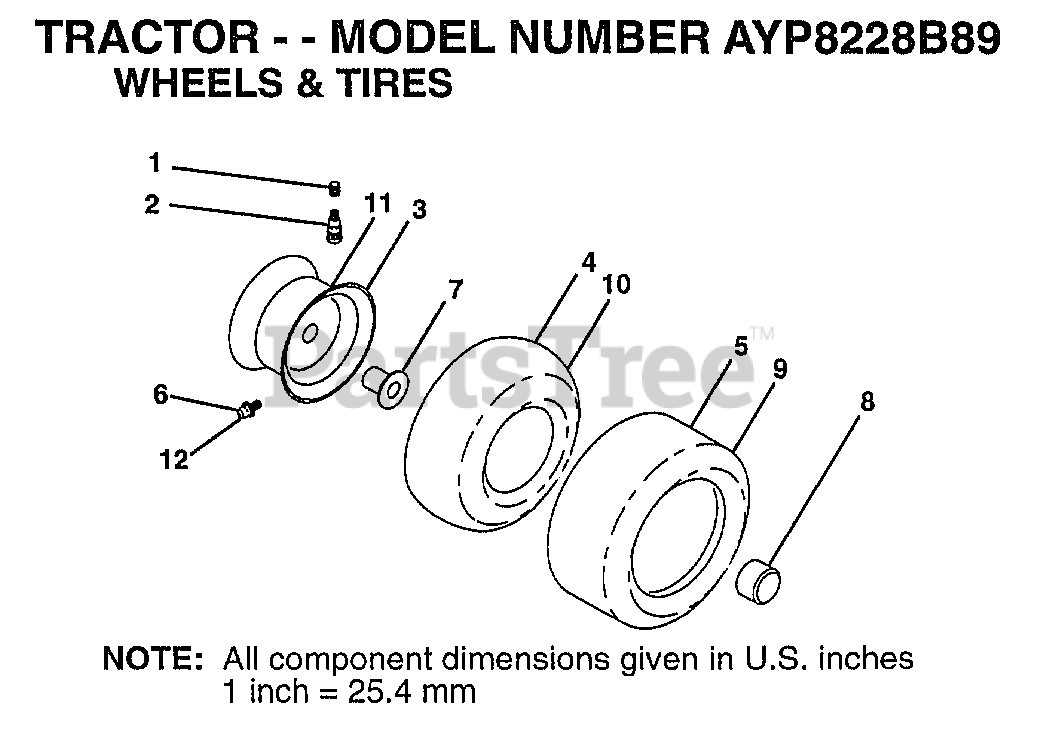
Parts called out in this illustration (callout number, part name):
1	VALVE CAP
2	VALVE STEM LT
3	"RIM ASM 8"" FRT"
4	TUBE.16X6.5/7.5-8
6	FITTING LT
7	"FLANGE, BEARING"
8	HUB CAP
10	TUBE.23X8/10-12
11	"RIM ASM 12"" REAR"
12	ZERK FITTING M
